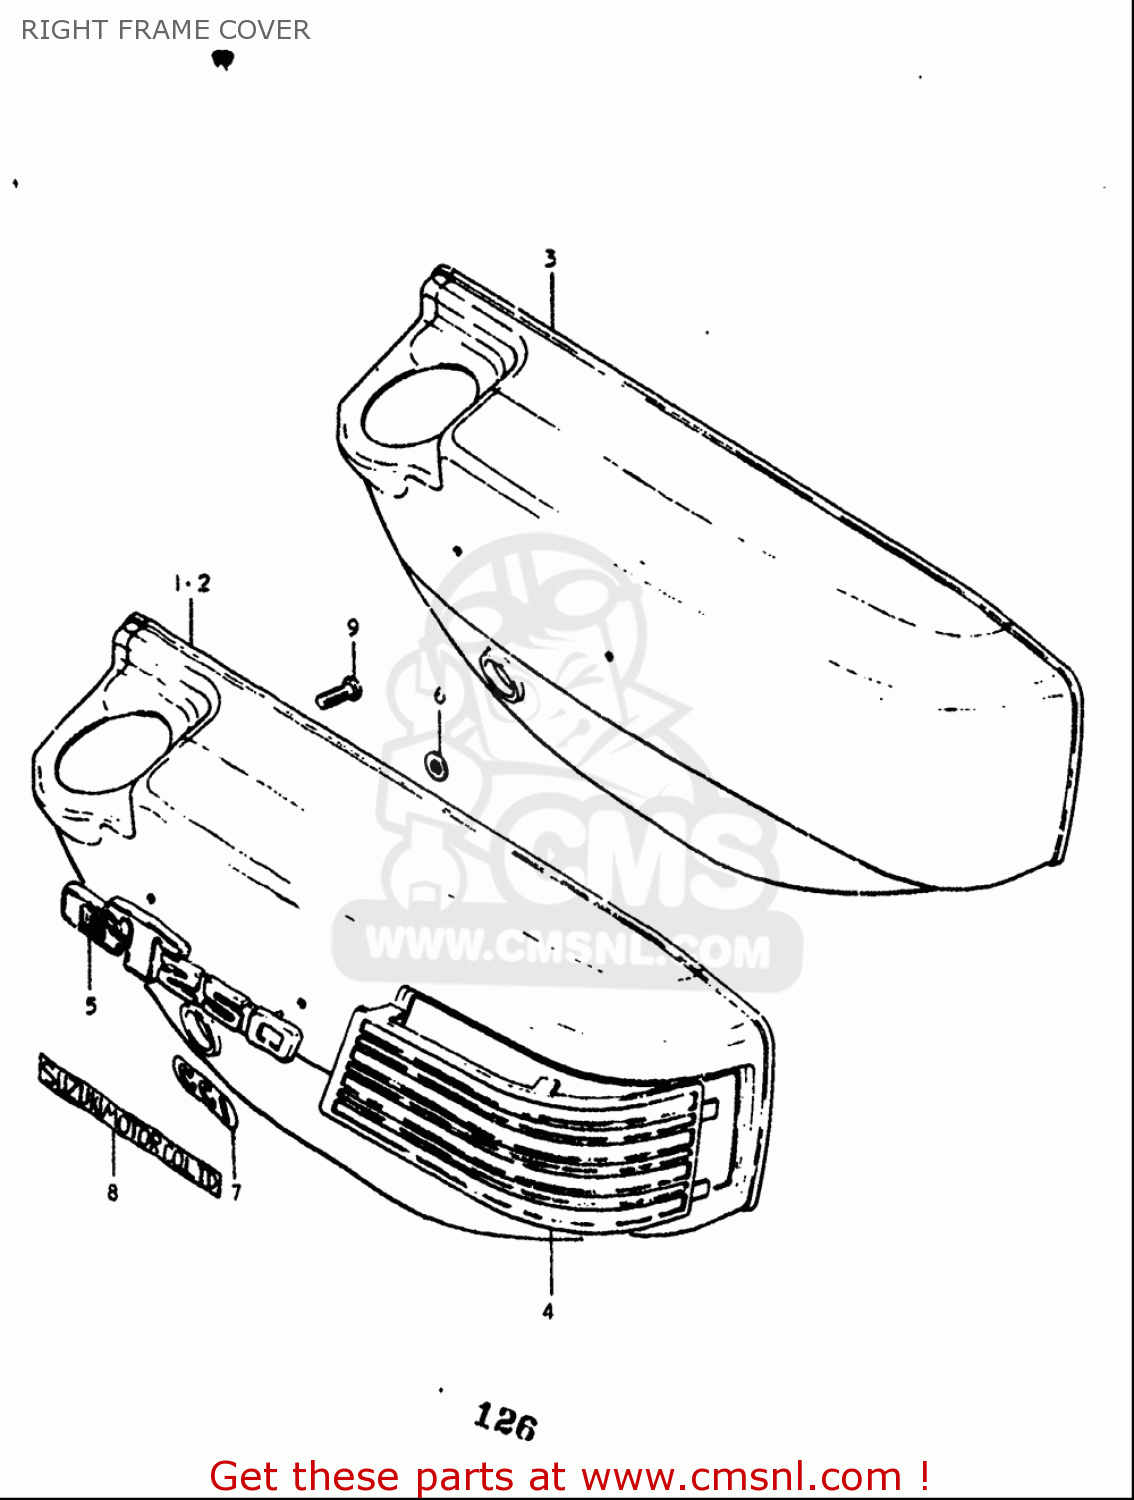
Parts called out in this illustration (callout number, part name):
6	NUT
7	EMBLEM,CCIS
9	SCREW
